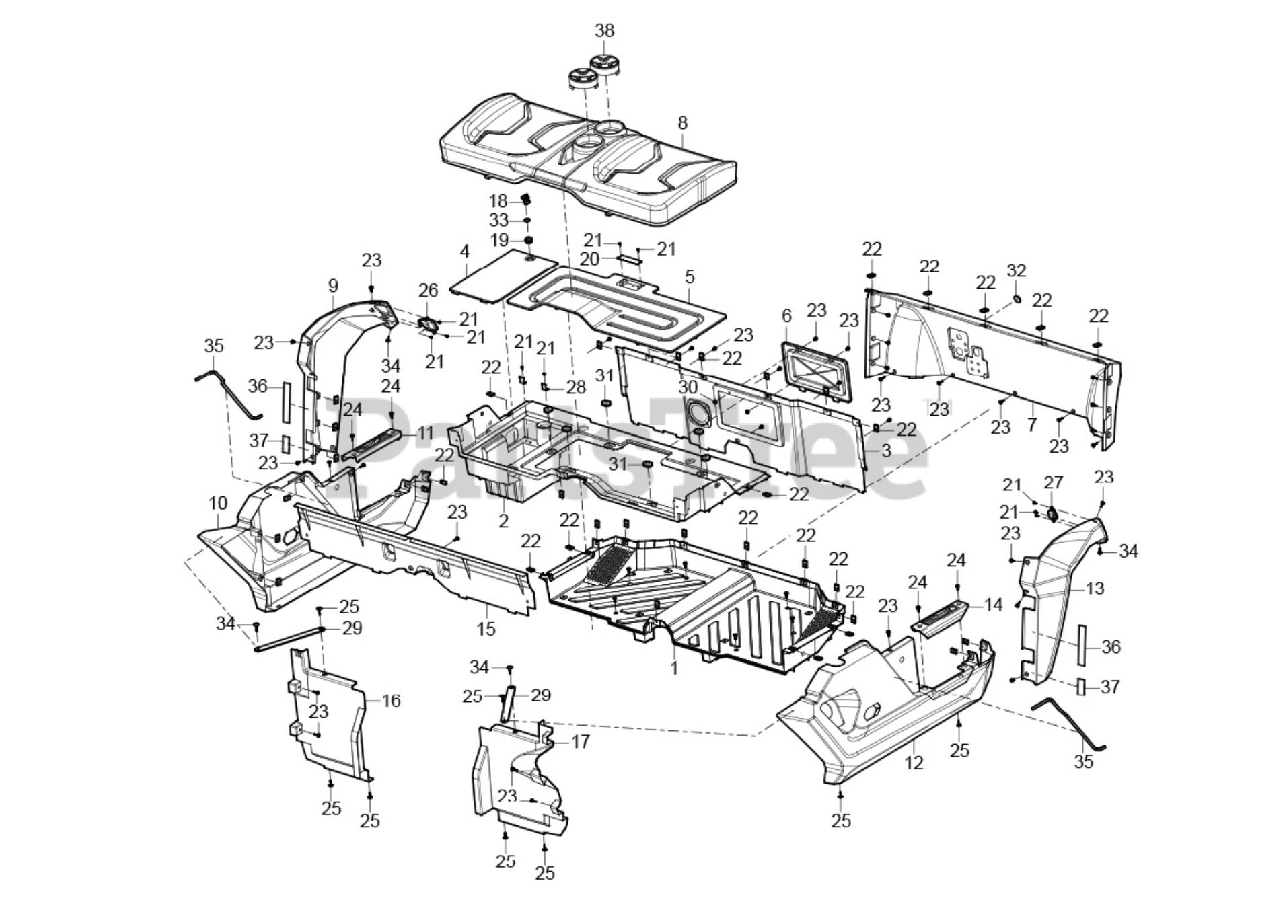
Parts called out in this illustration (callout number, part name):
2	SEATING SUPPORT ?
3	SEATING SUPPORTII
4	COVER - BATTERY
5	COVER - ENGINE
6	COVER - BATTERY BOx
7	FRONT PANEL FOOT REST
8	BOTTOM SEAT KIT
9	SIDE PANEL - FRONT LEFT
10	SIDE PANEL - MIDDLE LEFT
11	SIDE PROTECTOR - LEFT
12	SIDE PANEL - MIDDLE RIGHT
13	SIDE PANEL - FRONT RIGHT
14	SIDE PROTECTOR - RIGHT
15	SEATING PROTECTOR
16	REAR MUDGUARD II
17	REAR FENDER
18	LOCK - BATTERY BOx COVER
19	RUBBER WASHER
20	LOCK - ENGINE COVER
21	SCREW - CROSS HEAD SELF DRILLING ST3.9x10
22	CLAMP NUT M6x6
23	Socket Hex Flat Head Bolt M6x16
24	BOLT HExAGON SOCKET FANGLE M6x20
25	Cross Large Plate Head Screw M6x16
26	TURN LIGHT - FRONT LEFT
27	TURN LIGHT - FRONT RIGHT
28	STARTER RELAY BRACKET PLATED
29	SIDE PLATE SUPPORT ?
30	HExAGON FLANGE HEAD NUT M6
31	RUBBER WASHER 8x17
32	BRAKE PEDAL DUST PAD
33	Flat Washer 15x 22x1.5
34	HExAGON SOCKET HEAD CAP SCREWS M6x16
35	DOOR SEAL 1
36	DOOR SEAL 2
37	DOOR SEAL 3
38	CUP HOLDER
